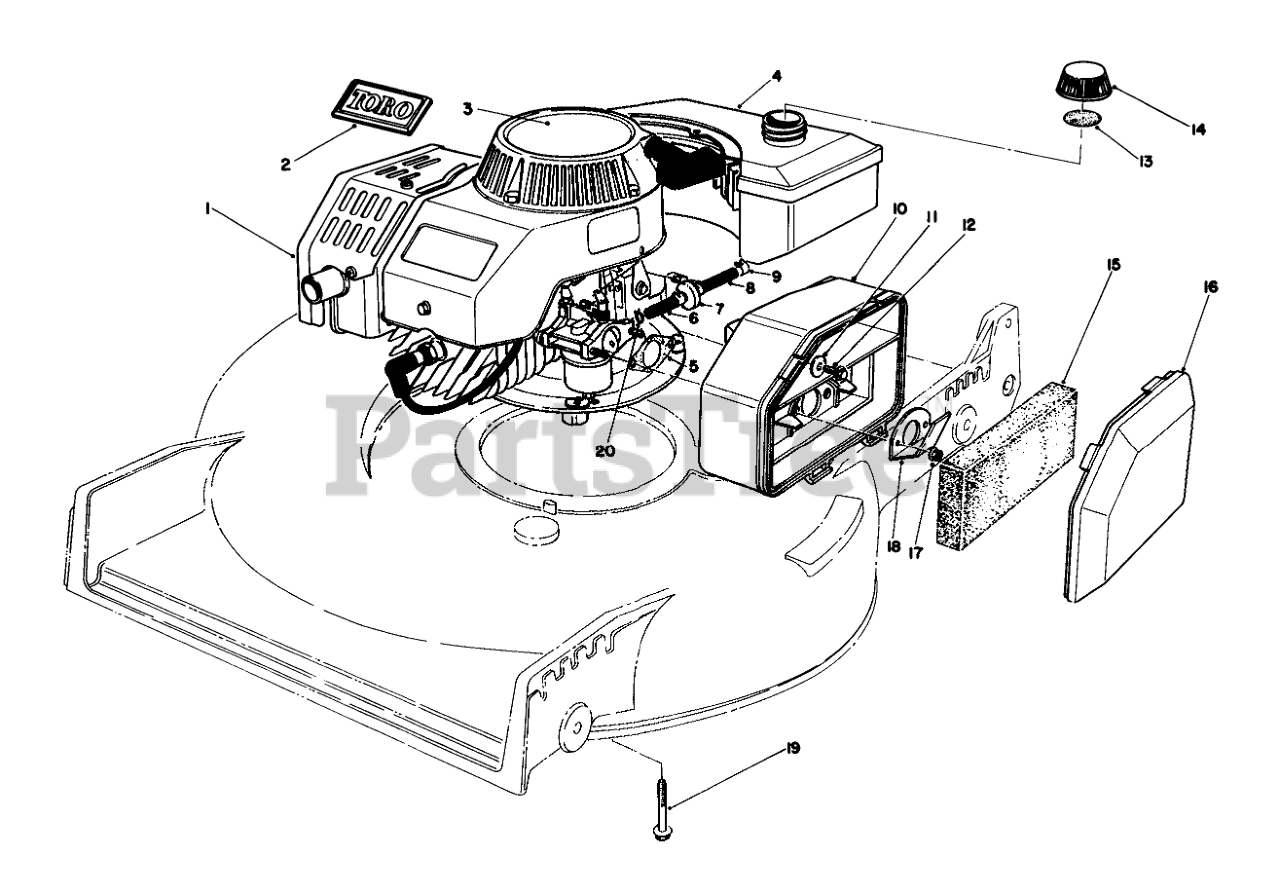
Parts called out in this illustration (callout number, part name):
1	Engine
2	TORO LOGO PLT
3	DECAL
4	Gas Tank Assembly
5	GASKET-AIR CLEANER
6	HOSE-FUEL
7	FILTER-FUEL
8	HOSE-FUEL
9	CLAMP-FUEL LINE
10	AIR CLEANER
11	WASHER-FLAT
12	SCREW-HH
13	GAS CAP GASKET
14	Gas Cap Assembly (Incl. Ref. #13)
15	FILTER
16	AIR CLEANER COVER
17	NUT-LOCK
18	SPIT BACK DEFLECTOR
19	SCREW-HHF
20	CLAMP-HOSE
